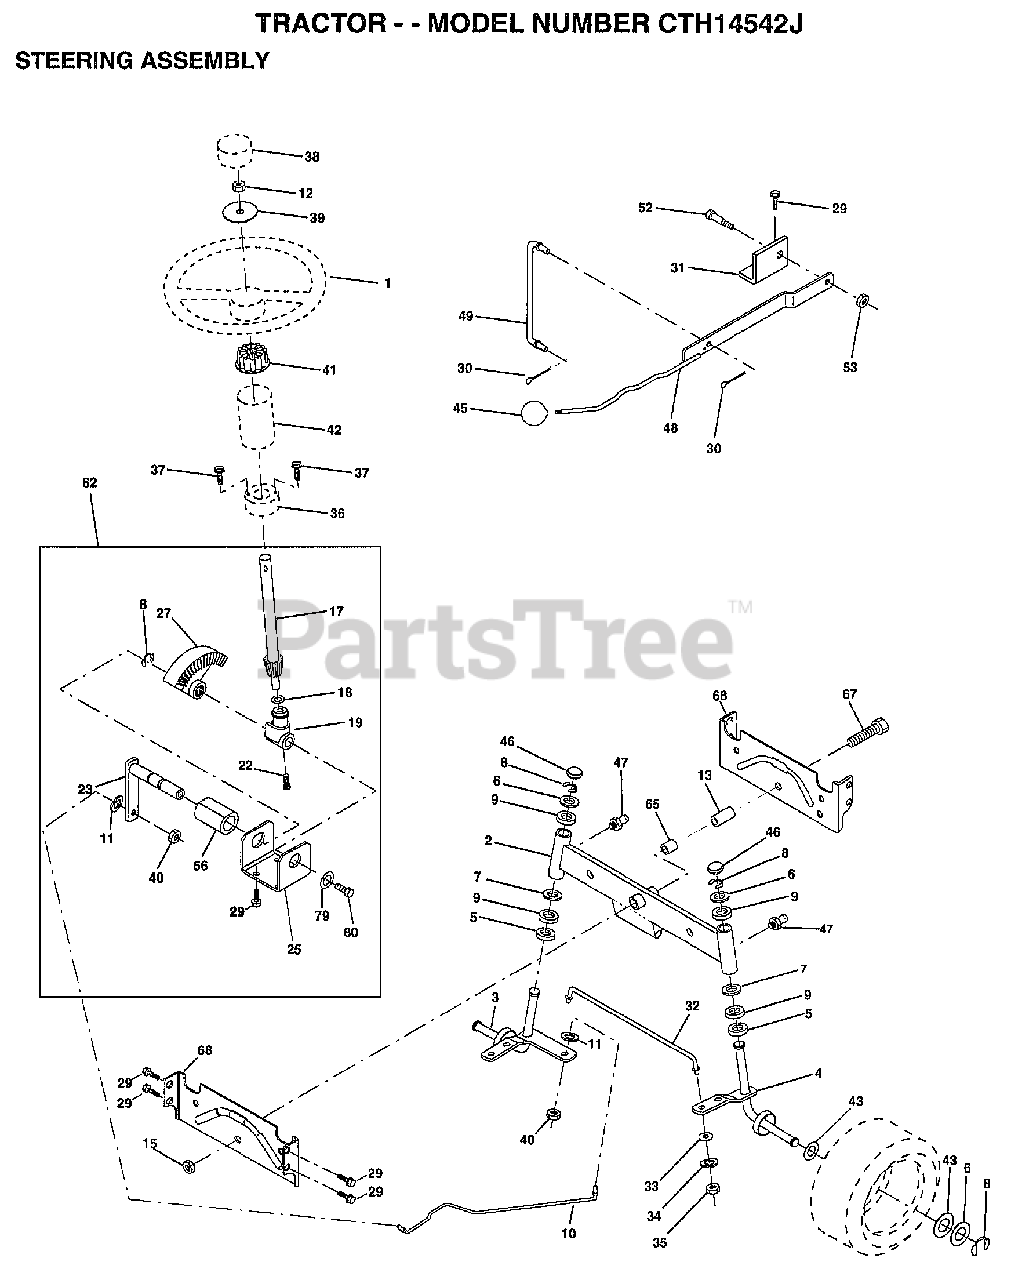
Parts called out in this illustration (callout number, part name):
1	WHEEL STR AYP BLK
2	AXLE ASM
3	SPINDLE.ASM.LH
4	"SPINDLE ASM,RH"
5	WASHER .T
6	WASHER
7	WASHER
8	RING
9	COL. SRTG. BEAR.
10	DRAGLINK-STAMPED
11	LOCKWASHER
13	BEARING AXLE
15	"NUT-LOC,FLANGE LT"
17	SHAFT ASM STEERNG
18	THRUST WASHER
19	SUPPORT.SHAFT.STEER
22	SCREW.HX.WSH.HD
25	BRKT-STEERING
27	GEAR SECTOR
29	SCREW
30	COTTER PIN
31	BRKT.PVT.MAN.LVR.
32	ROD.TIE.19.75
33	WASHER M
34	LOCKWASHER
35	NUT.LOCK.5/16-24
36	BUSHING.STRG.3/4
37	"SCREW-TT,10-32 FL"
38	CAP STEER AYP
39	WASHER
40	GRIPCO NUT
41	ADAPTER LT
42	BOOT SHAFT STEER
43	WASHER
45	KNOB T (1/2-HOLE)
46	CAP
47	ZERK M
48	LEVER.ASM.CLUTCH
49	LINK CLTCH W/NUTS
52	"BOLT, SHOULDER LT"
62	KIT.STEER.ASM
65	SPACER AXLE
66	"BEARING-ARM,PITMA"
67	BOLT
68	BRACE AXLE
79	WASHER
80	BOLT.HX.NYLON3/8-16X3/
